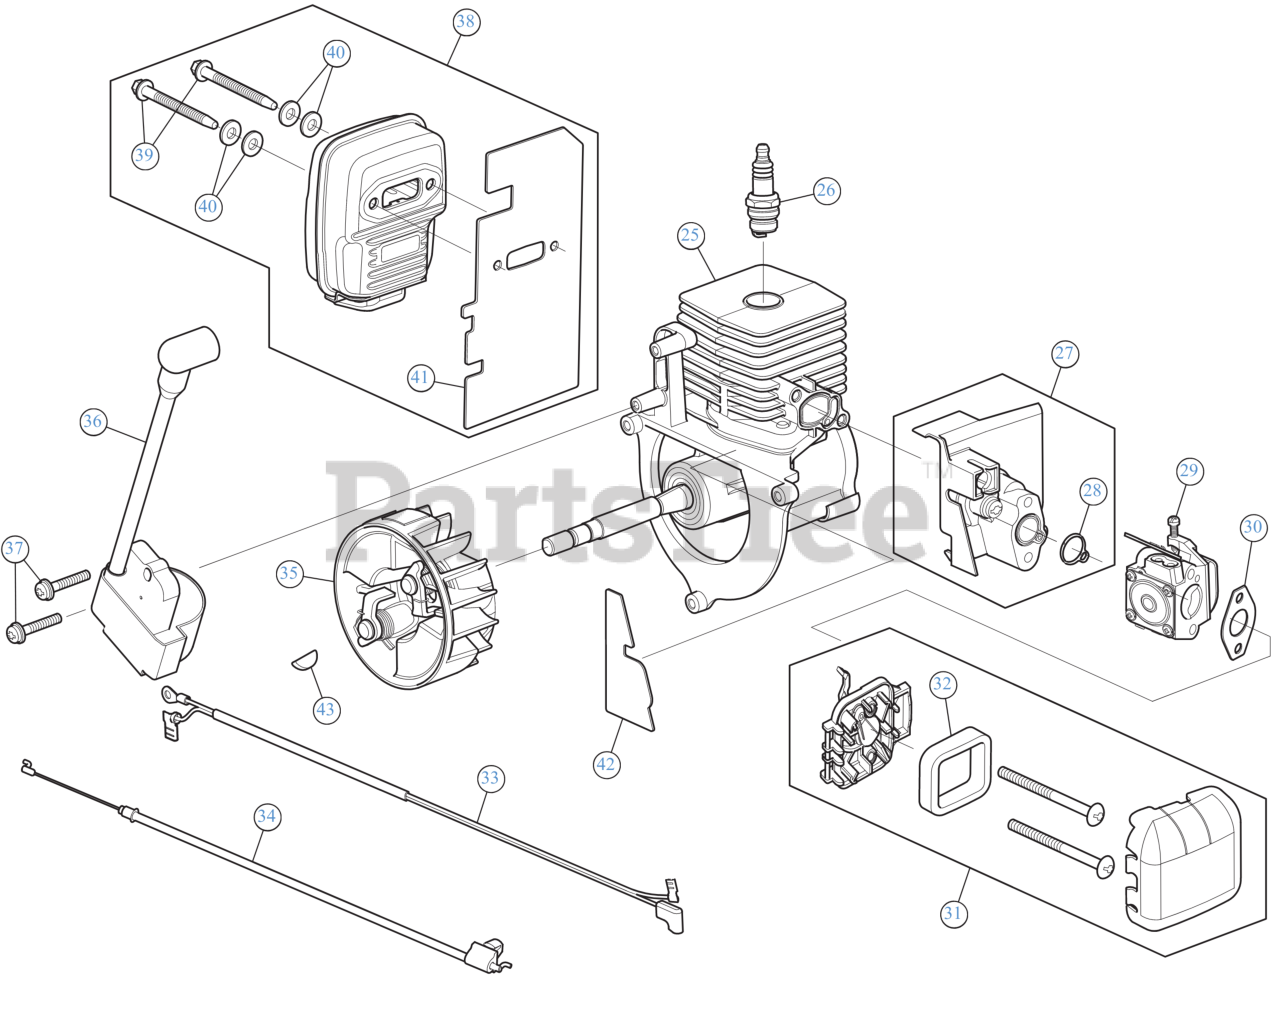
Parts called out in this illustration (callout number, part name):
25	SHORT BLOCK
26	SPARK PLUG
27	INTAKE ASSEMBLY
28	O-RING
29	CARBURETOR
30	GASKET CARB
31	AIR CLEANER ASSEMBLY
32	AIR FILTER
33	WIRE LEAD
34	THROTTLE CABLE
35	FLYWHEEL ASSEMBLY
36	MODULE
37	SCREW 8-32X.750
38	MUFFLER ASSEMBLY
39	MUFFLER SCREW
40	WASH, FLAT .480X.1
41	GASKET
42	SHORTBLOCK GASKET
43	WOODRUFF KEY #403-.125 x .375
